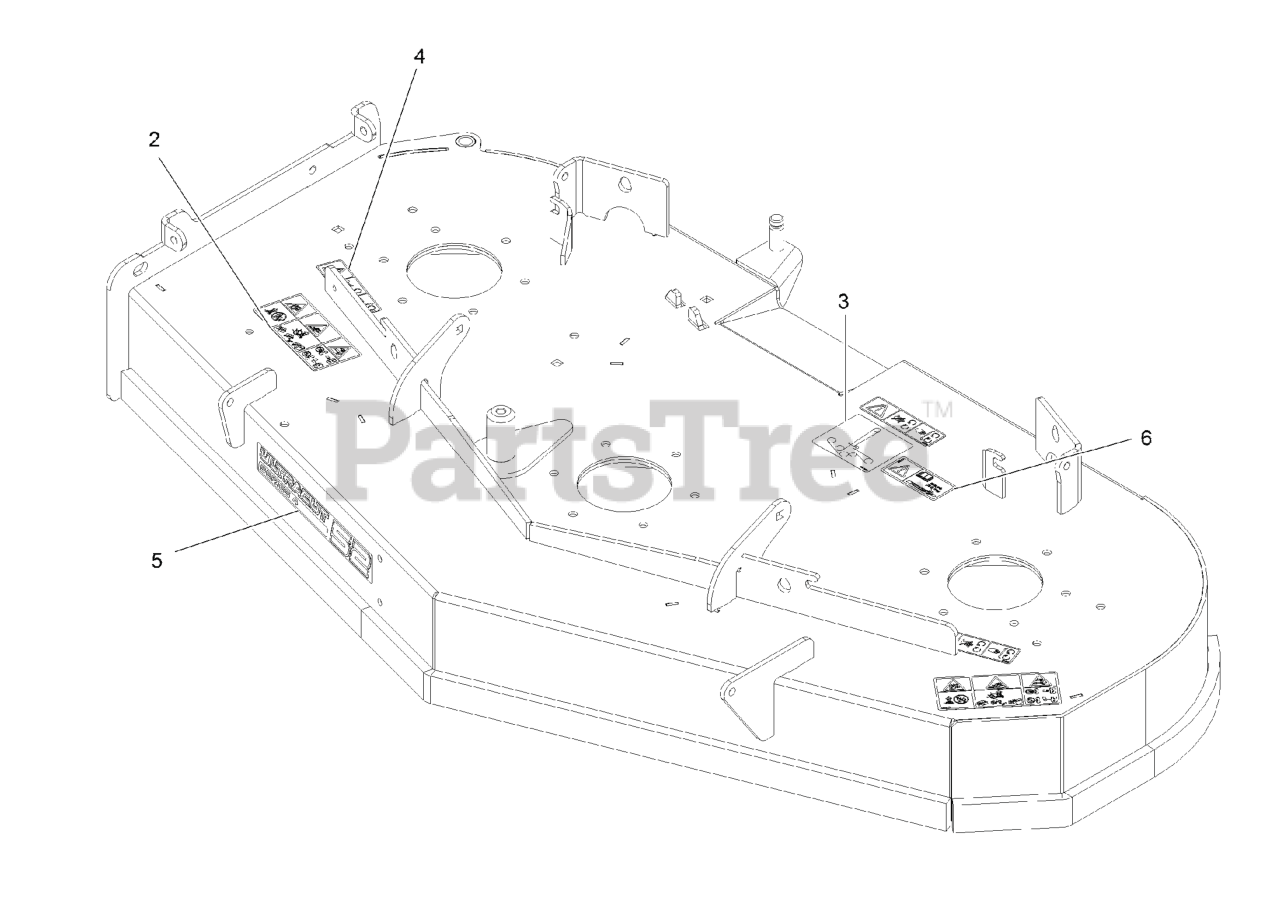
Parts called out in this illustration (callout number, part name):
2	DECAL-WARNING THROWN OBJ
3	DECAL-BELT ROUTING
4	DECAL-COVER, MISSING
5	DECAL, 524
6	DECAL-TORQUE, BOLT
